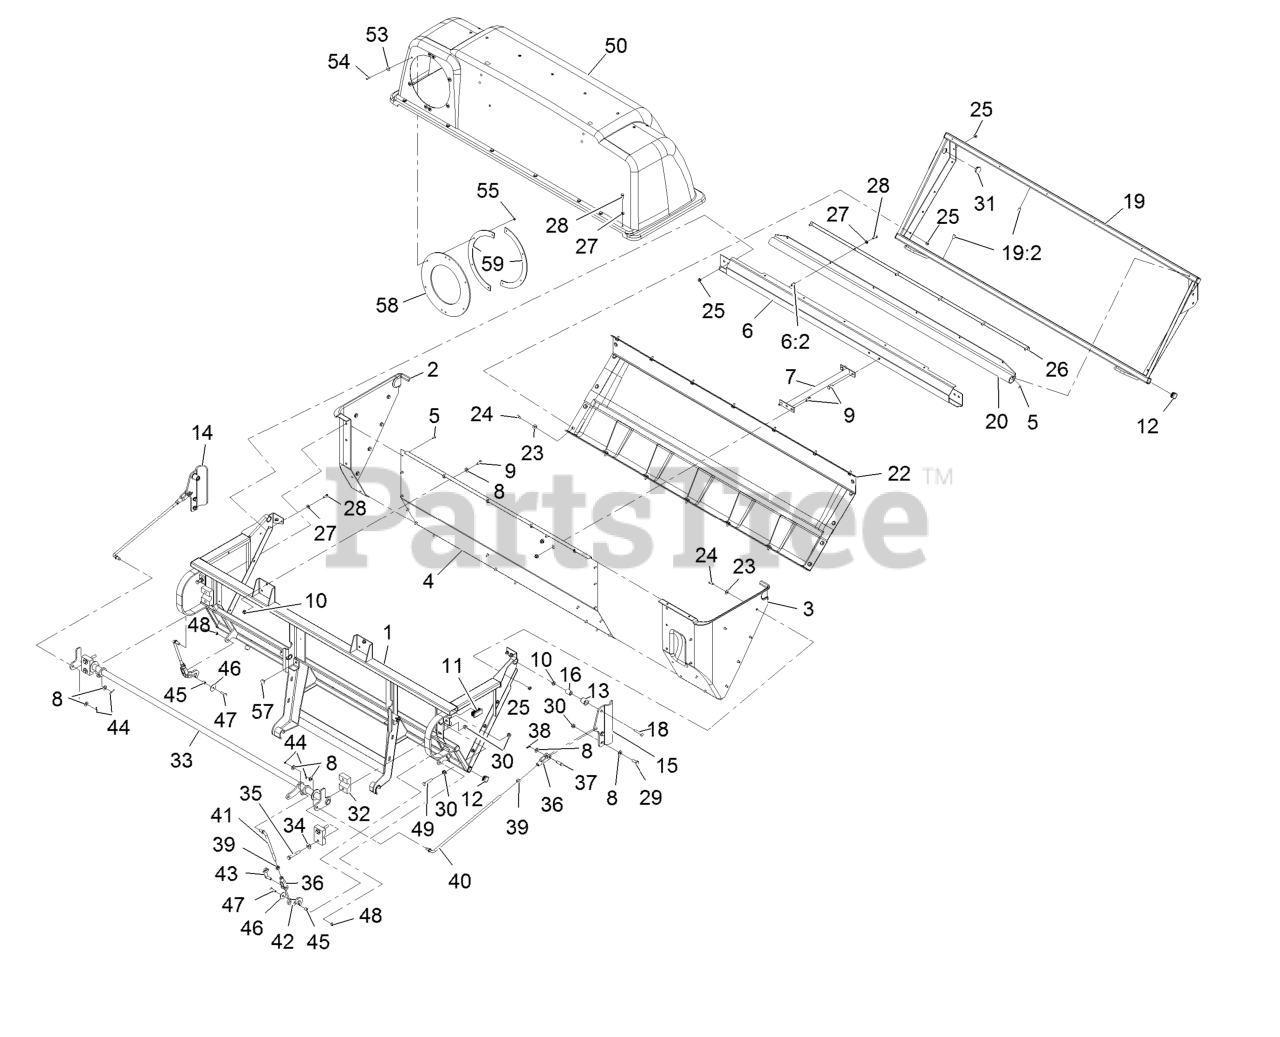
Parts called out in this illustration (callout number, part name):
2	Panel-Bagger, RH
3	Panel, Bagger LH
4	Sheet, Wall
6	Rear Crossmember ASM
6:2	Insert-Nut
8	Washer-3/8 SAE
9	Screw-HH 5/16-18 X 3/4
10	Nut-Whizlock 5/16-18
13	Bushing
14	Arm-Hinge, RH
15	Arm, Hinge LH
16	Pin-Pivot, Hinge
18	Screw-HH 3/8-16 X 1 3/4
19	Door ASM
19:2	Insert-Nut
20	Seal-Door Hinge
22	Bag And Bottom Panel ASM
23	Washer-1/4 Std
24	Screw-HH 1/4-20 X 5/8
25	Nut-Whizlock 1/4-20
26	Strap-Hold Down
27	Washer-1/4 SAE
28	Screw-HH 1/4-20 X 3/4
29	Screw-HH 3/8-16 X 1
30	Nut-Whizlock 3/8-16
31	Plug-Dome
32	Half-Block, Bearing
33	Link-Intermediate
34	Washer-3/8 Std
35	Screw-HH 3/8-16 X 2 1/2
36	Yoke-Linkage, Brake
37	Pin-Clevis 3/8 X 1 1/8
38	Hairpin-Cotter
39	Nut-Hex 3/8-24
40	Link-Hinge
41	Link-Handle
43	Pin-Clevis Spring 3/8
44	Pin-Cotter 1/8 X 3/4
47	Screw-HH 1/4-20 X 1
48	Nut-Nyloc 1/4-20
49	Screw-HH 3/8-16 X 1 3/4
50	ASM,Hood Dump
54	Screw-PPH #10-24 X 7/8
55	Nut-Nyloc #10-24
58	Seal-Tube
59	Clamp-Seal
